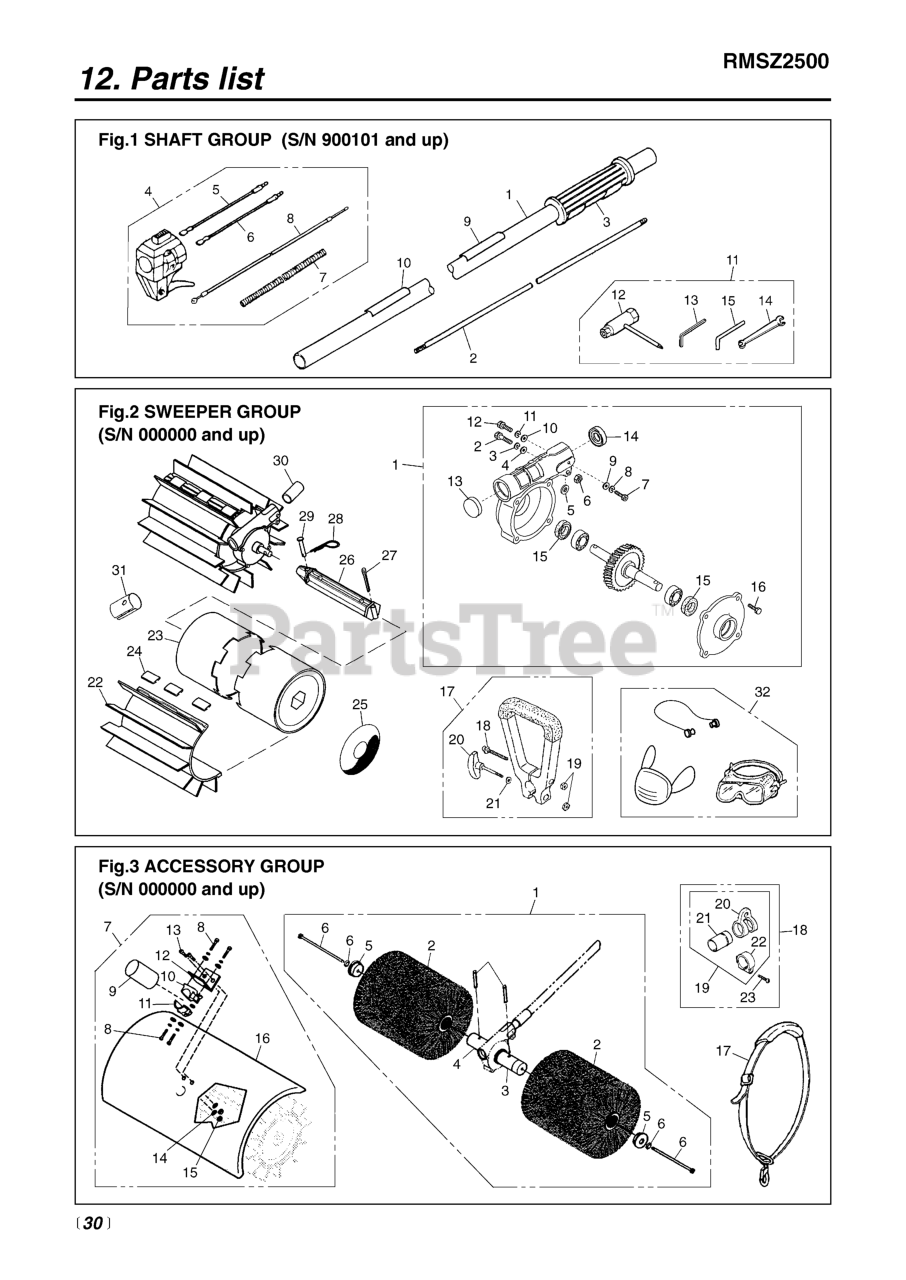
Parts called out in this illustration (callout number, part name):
1	PIPE COMPLETE
3	GRIP (RPLS 3577-32140 & 3220-
5	CORD (A), BLACK
6	CORD (B), RED
7	TUBE (RPLS 4900-72141)
8	CABLE (RPLS 5580-83100)
9	NAMEPLATE
10	PLATE, CAUTION
12	SOCKET
13	WRENCH (TOOL)
14	SPANNER, 8 X 10 (RPLS 2540- )
15	BAR
A2	BOLT, M6 x 30
A3	SPRING WASHER
A4	WASHER, FLAT
A5	WASHER, FLAT
A6	NUT, M6 X 5
A7	BOLT, M5 x 12
A8	WASHER, SPRING M4 x 1.3
A11	WASHER, SPRING M4 x 1.3
A12	SCREW
A13	PLUG, HOUSING
A16	SCREW
A17	HANDLE ASSY (RPLS 99909-33009)
A24	CLIP, BELT
A25	LABEL, REDMAX
A26	AXLE, DRUM (RPLS -33016)
A27	PIN, COTTER
A28	PIN, HITCH
A29	PIN, CLEVIS (RPLS -33018)
A30	PROTECTOR, TUBE
A32	SAFETY KIT
B1	BRUSH SWEEPING ATTACH (NYLON)
B2	BRUSH, NYLON
B3	ADAPTOR, GEAR SHAFT, LH
B4	ADAPTOR, GEAR SHAFT, RH
B6	KIT, BRUSH HARDWARE
B7	DEBRIS SHIELD ASSEMBLY
B10	BRACKET, HANDLE
B11	CAP, LOWER
B12	BRACKET, SHIELD
B18	HANGER ASSEMBLY
B19	HANGER COMPLETE
B20	HANGER
B21	CLAMP
B22	SLEEVE
B23	SCREW, M5 x 25
